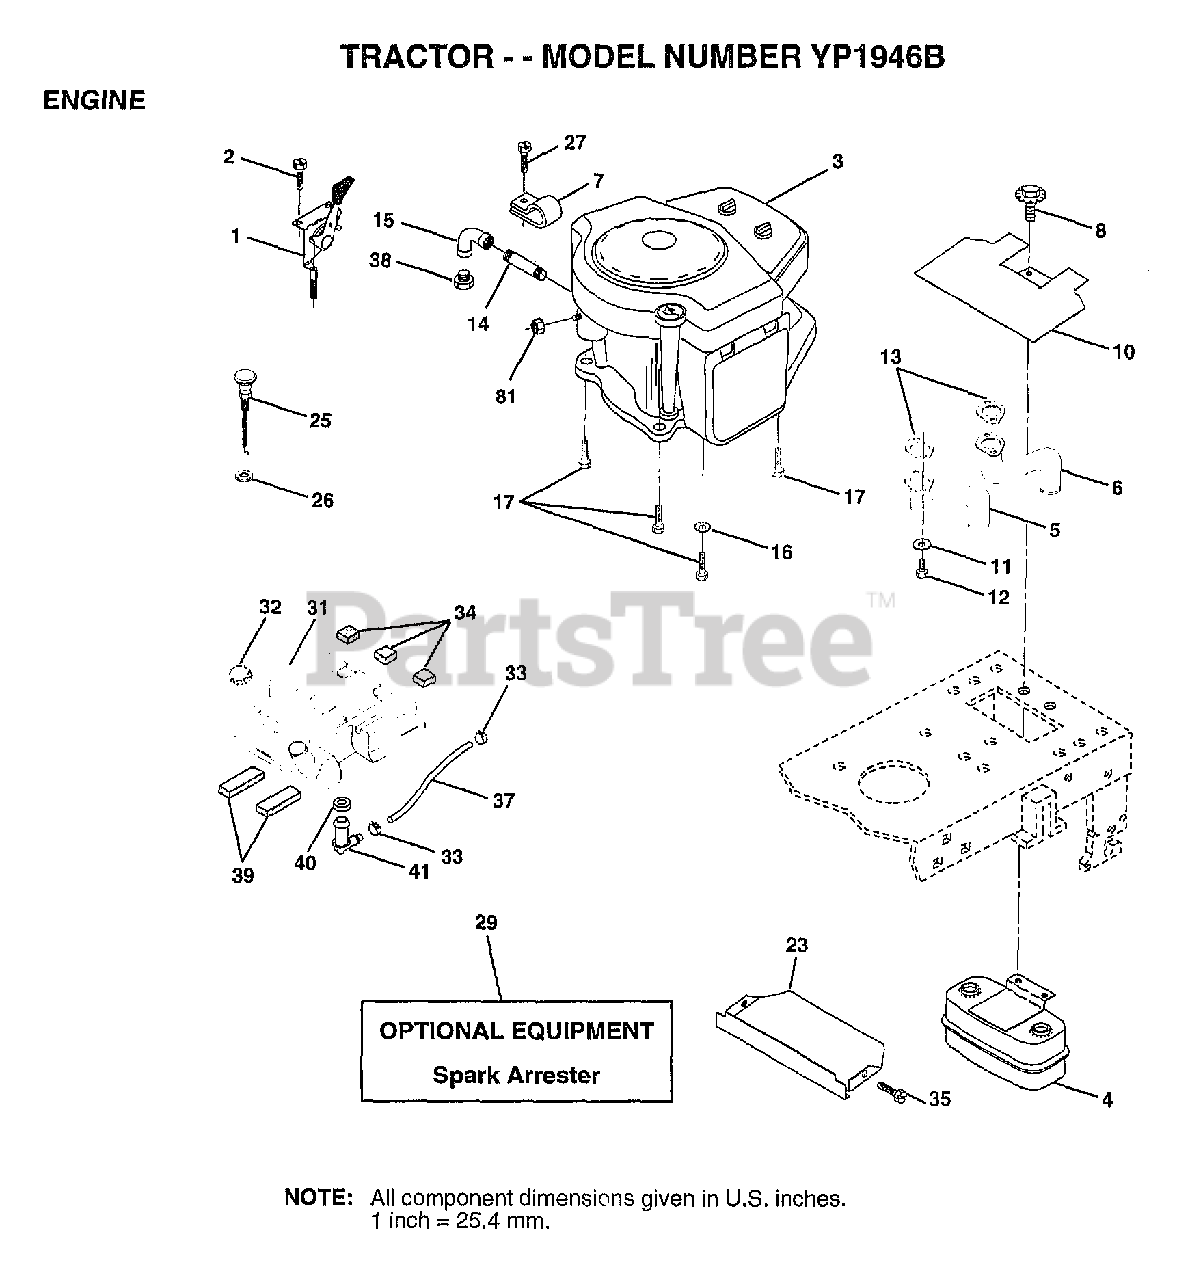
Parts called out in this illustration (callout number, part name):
1	CONTROL THRT 35.5
2	SCREW LT
4	MUFFLER.TW.LOTONE
5	EXHAUST.B&S.18.LH
6	EXHAUST.B&S.18.RH
7	CLAMP.TUBE.DBL.EN
8	BOLT.5/16-18.UNC
10	SHIELD.HEAT.
14	PIPE NIPPLE LT
15	ELBOW
16	LOCKWASHER
17	SCREW LT
23	SHIELD.BRN/DBR.GD
25	CONTROL.CHOKE.37
26	"NUT,KEPS 3/8-24IM"
27	"SCREW-TT,10-32 FL"
31	TANK FUEL REAR
32	CAP ASM FUEL
33	HOSE CLAMP
34	PAD-SPACER LT
35	SCREW
37	FUEL LINE T
39	PAD IDLER TI
40	BUSHING OUTLET T
41	STEM.TANK.FUEL
81	NUT
